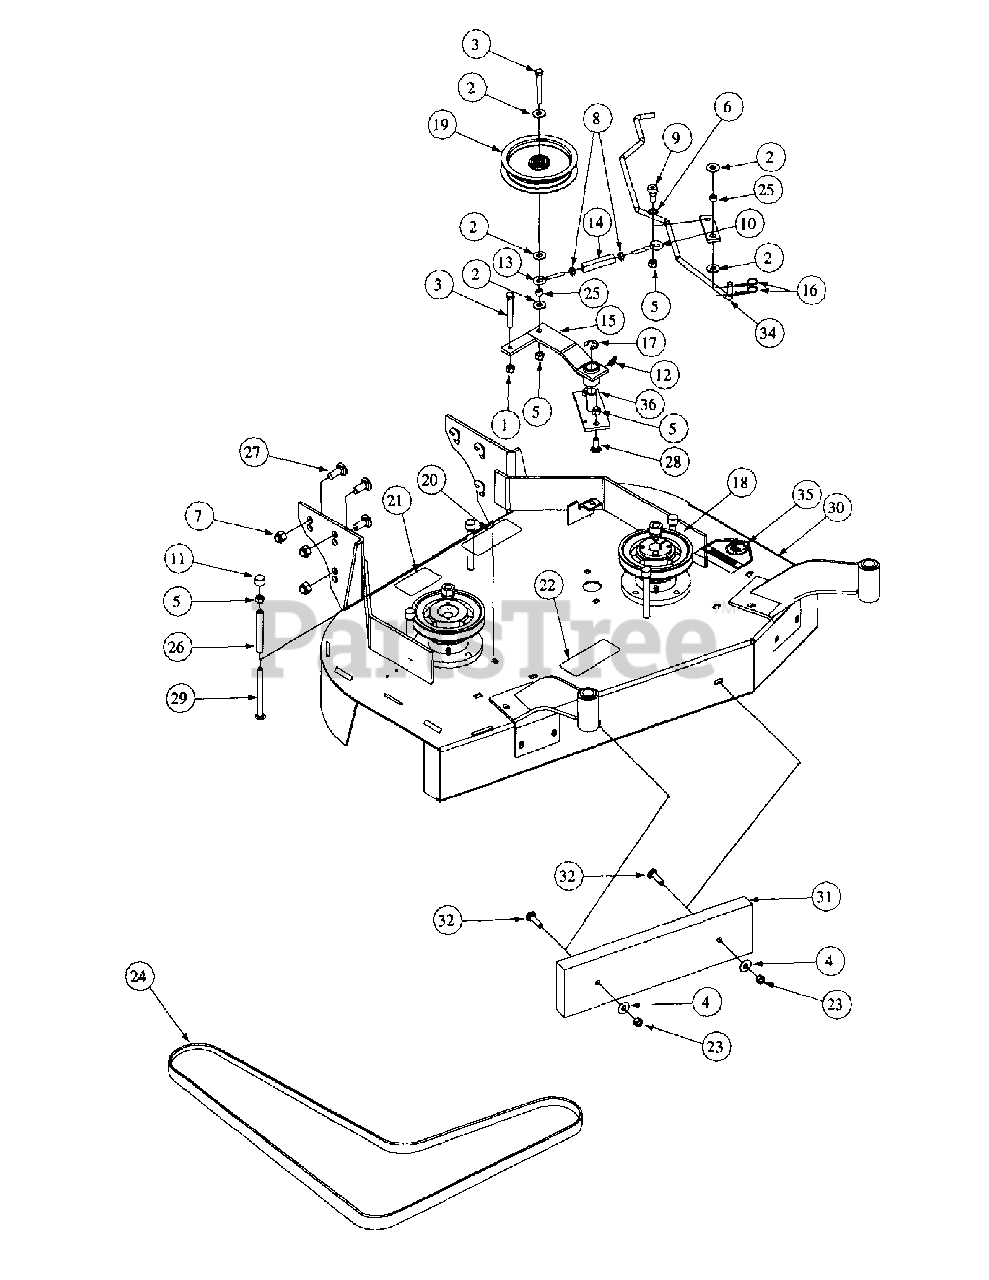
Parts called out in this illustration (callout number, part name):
1	Hex Nut, 3/8-16
2	Flat Washer, 3/8 Zinc
3	Hex Cap Screw, 3/8-16, 1
4	Flat Washer, 3/8 Zinc
5	Lock Nut, Nylon Insert, 3/8-16
6	Shim Washer
7	Lock Nut, Nylon Insert, 1/2-13
8	Hex Nut, 5/16-18
9	Shoulder Bolt
10	Eye Bolt, Right Hand
11	Cap, Black Vinyl
12	Grease Fitting, 1/4-28 x 3/16
13	Eye Bolt, Left Hand
14	Turnbuckle
15	Idler Arm
16	Hair Pin, 3/8"-1/2"
17	E-Ring, Retainer
18	Pulley Deck
19	Idler Deck Take-up
20	Decal Rotating Blade
21	Decal Warning Safety
22	Decal, Warning Shield Missing
23	Lock Nut, 3/8-16
24	Belt Drive
25	Turnbuckle, Sleeve
26	Spacer, Belt Guide
27	Carriage Bolt, 1/2-13 x 1-1/4
28	Carriage Bolt, 3/8-16 x 2
29	Carriage Bolt, 3/8-16 x 4.5
30	Deck 36"
32	Carriage Bolt, 3/8-16 x 1-1/2
34	Rod Clutch Link
35	Decal, Danger Hands and Feet
36	Idler Base
